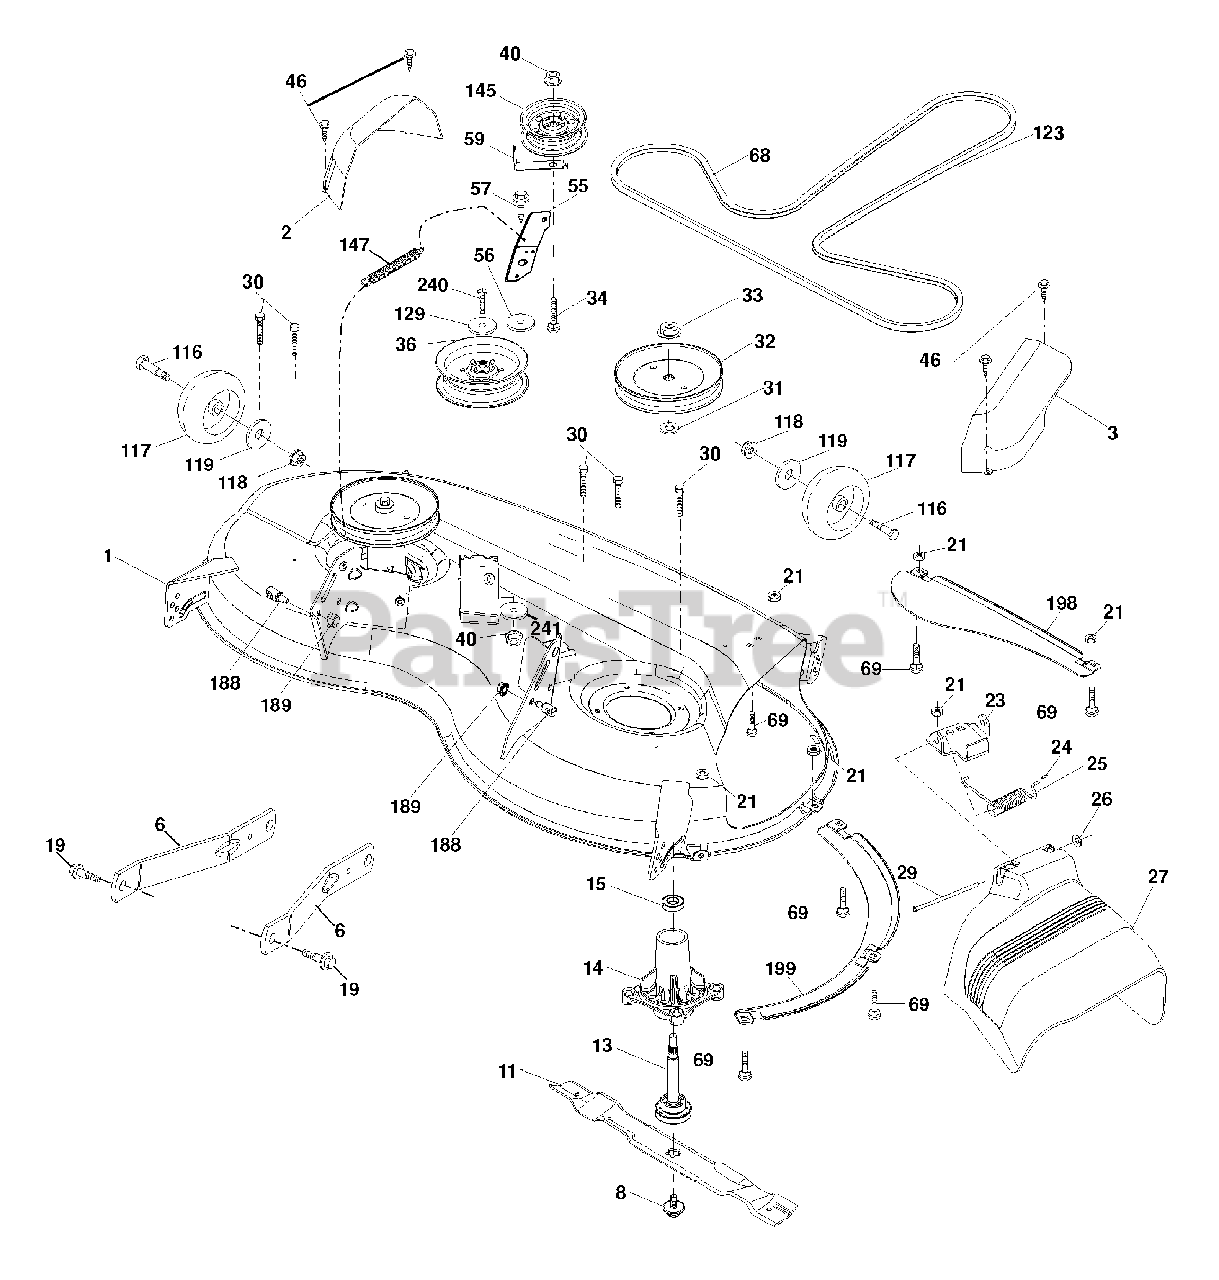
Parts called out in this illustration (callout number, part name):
1	Mower Housing
2	Cover Mandrel LH
3	Cover Mandrel RH
6	Arm Suspension
8	Bolt/Washer asm 7/16-20 unf
11	Blade Mower
13	Shaft Assembly, Mandrel
14	Housing, Mandrel
15	Bearing, Ball, Mandrel
19	Bolt, Shoulder
21	Nut
23	Bracket, Deflector
24	Cap, Sleeve
25	Spring, Torsion, Deflector
27	Shield, Deflector
29	Rod, Hinge
30	Screw Thdrol Rolling Wsh Hd
31	Washer, Spacer
32	Pulley, Mandrel
33	Nut, Toplock, Flanged
34	Bolt Carr Sh. 3/8-16 x 1-1/2 Gr. 5
36	Pulley, Idler, Flat
38	Keeper Belt LH Mandrel
40	Nut 3/8-16 UNC
55	Arm, Idler
56	Spacer, Retainer
57	Screw Hexwsh Thd 3/8-16 x 1
59	Guard, Tuv Idler (94)
60	Arm Brake Mower
62	Bolt 3/8-16 UNC x 2
63	Arm Brake Mower
64	Linkage Brake
68	V-Belt
69	Bolt
113	Screw 5/16-18
116	Bolt, Shoulder
117	Wheel, Gauge
118	Nut, Crownlock 3/8-1
119	Washer 13/32 x 1-1/4 x 12 Ga.
129	Washer 13/32 x 13/16 x 12 Ga.
145	Pulley Idler
188	Stud Fastener
189	Nut Lock Hex Flange
198	Baffle Center Front
199	Baffle Front RH
240	Bolt 3/8-16 x 2-1/4 Gr. 5
241	Washer 13/32 x 2 x 10 Ga.
